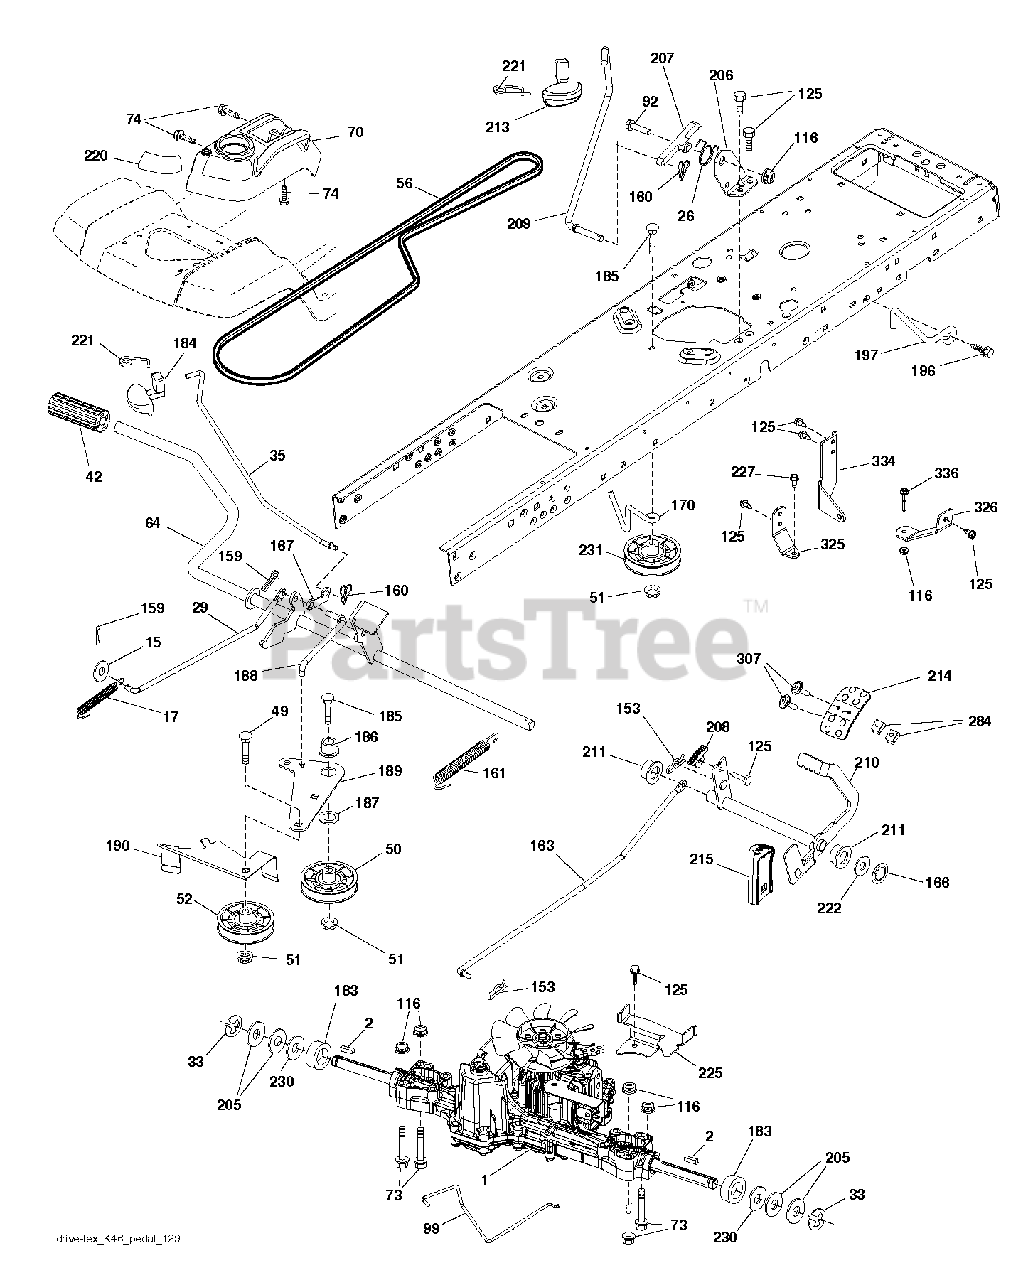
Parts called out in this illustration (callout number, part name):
1	RP TRANSAXLE (K46CR) ETC.PDL
2	SQUARE KEY
15	WASHER
17	SPRING.BRAKE.K46.GREEN
26	SPRING.RETURN.CRUISE
29	ROD.BRAKE.K46
35	ROD .BRAKE. PARKING. GT. HUSQ.
42	PEDAL COVER T
50	IDLER.FLAT.910.OFFSET
51	NUT LOCK FLG 3/8-16 UNC
52	IDLER.V-GROOVE.910.OFFSET
56	V-BELT.MOWER.92.40.42/K46
64	SHAFT.ASM.PEDAL.BRK.CNTR
70	CONSOLE.ASM.RH.GT.FC.HUSQ
73	BOLT HEX 5/16-18 GR 5
74	SCREW.HI-LO.CONSOLE
92	BOLT
99	ROD.SPRING.BYPASS.K46.LT.Z
116	NUT LOCK HEX FLANGE 5/16-18
125	SCREW
153	RETAINER M
159	COTTER PIN
160	RETAINER CLIP
161	SPRING, RETURN LT
163	ROD.CONTROL.K57R.K46
166	NUT.PUSH.625
167	LATCH.BRAKE.SPRING
170	KEEPER.CENTER SPAN.1.688
183	SPACER AXLE
184	HANDLE.PARKING.BRAKE.H (BLK)
186	SPACER.RETAINER
187	WASHER 12/32X2X10GA
188	RP LINK.CLUTCH.GROUND.DRIVE
189	BELLCRANK.GROUND.DRIVE.TEX.
190	KEEPER.BELLCRANK.DRIVE
196	SCREW 3/8-16X1
197	LINK.CLUTCH.ANIT-ROTAT
206	BRACKET.MOUNT.CRUISE.LATCH
207	LATCH.CONTROL.CRUISE
208	GEAR.SECTOR.CONTROL.CR
209	ROD.CONTROL.CRUISE.GT.
210	ROCKER.ASM.PEDAL.CONTR
211	BEARING.NYLON
213	KNOB.CONTROL.CRUSIE.HU
214	PEDAL.FORWARD.HUSQVARNA.DEALER
215	PEDAL.REVERSE.TEX.GT.4
220	REFLECTOR.RH.TEX GT
221	RETAINER.SPRING.CLIP.H
222	WASHER 21/32 X 1-1/4 X 10 GA.
225	KEEPER.BELT.TRANSAXLE.K46
227	SCREW
230	WASHER.HARDENED
231	IDLER.V-GROOVE.1.688.OFFSET
284	NUT.U-CHNL.1/4-20.550DP.350PNL
307	SCREW.MACHINE.CR.1/4-20
325	BRACKET.TRQ.STP.46.20".TIRE.LH
326	BRCKT.PNT.TRQ.STP.46.20TIRE.RH
334	SWAY.ROD.BRACKET.K46.X431
336	Husqvarna TBD
